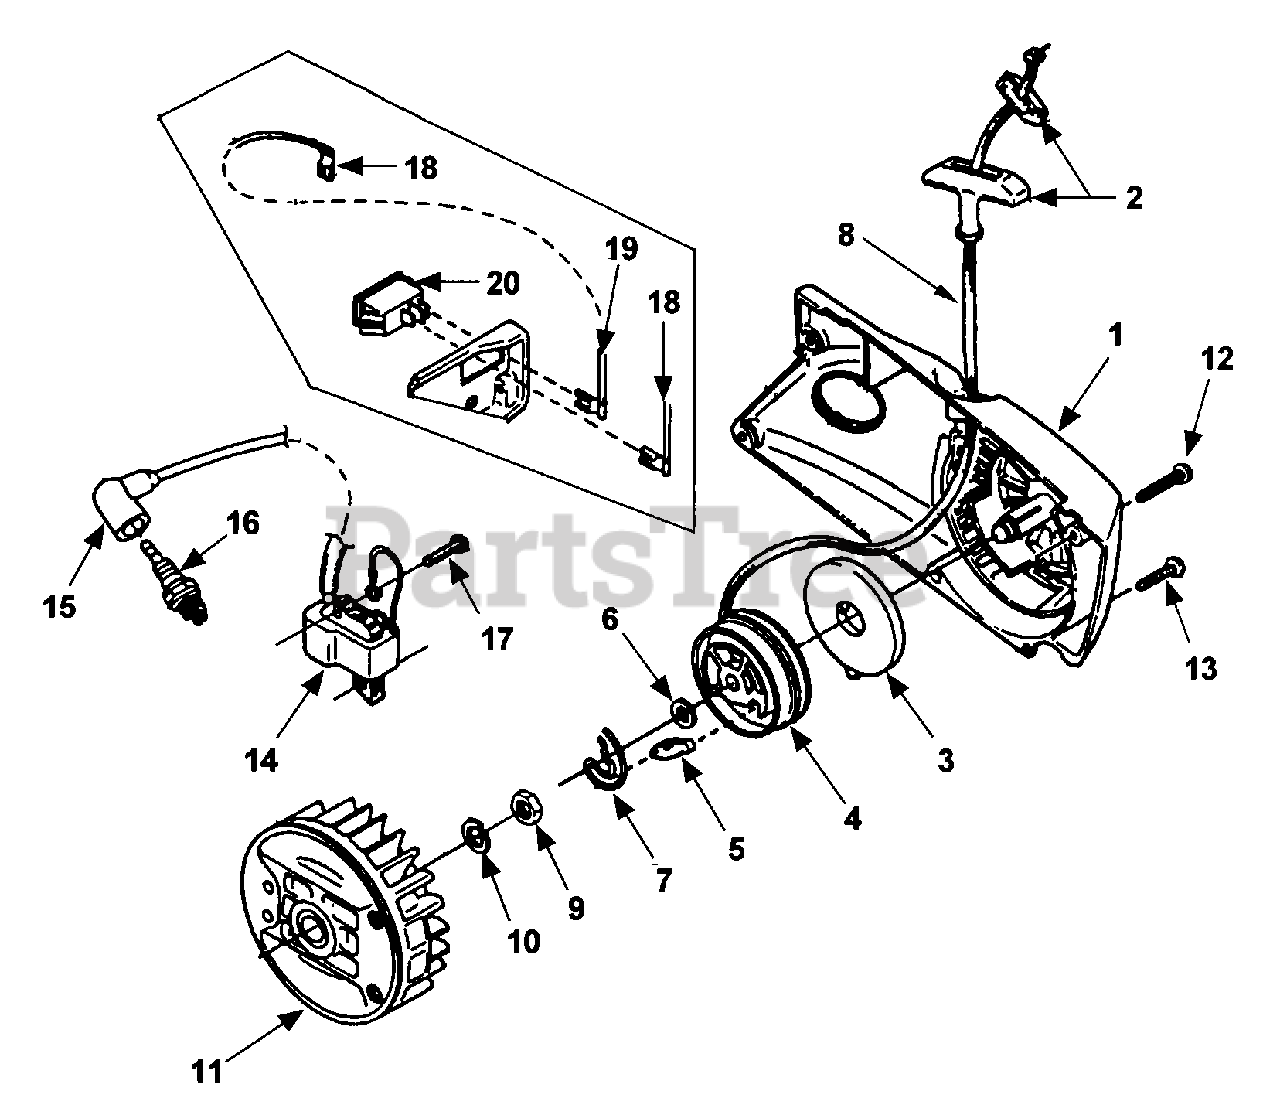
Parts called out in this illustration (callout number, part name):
1	STARTER
2	GRIP - Starter
3	SPRING & CONTAINER
4	PULLEY ASSEMBLY
5	WASHER - Thrust
6	PAWL - Starter
7	CLIP - Retainer
8	ROPE - Starter (45")
9	NUT - Jam (3/8-24)
10	WASHER - Lock (3/8")
11	ROTOR
12	SCREW - Truss Hd (10-24 x 1-1/4")
13	SCREW (10-24 x 3/4")
14	IGNITION MODULE (Sems/Walbro)
15	SPARK PLUG BOOT KIT
16	SPARK PLUG (CJ6Y)
17	SCREW - Pan Hd (8-32 x 5/8")
18	GROUND WIRE
19	IGNITION GROUND WIRE
20	SWITCH
